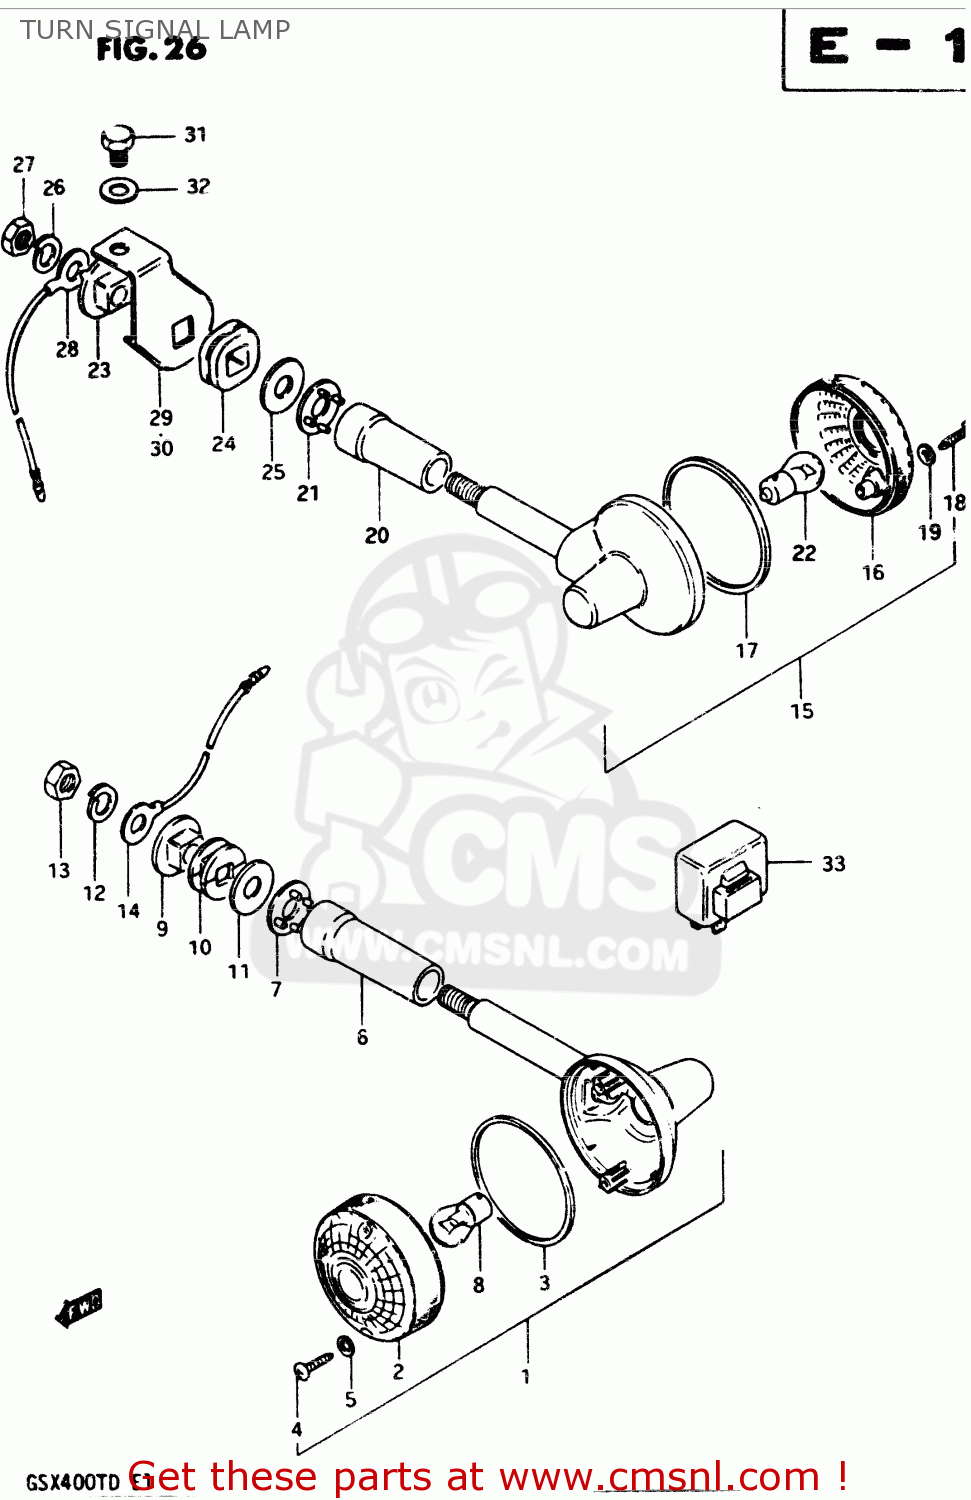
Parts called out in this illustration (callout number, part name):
1	LAMP ASSY FRON
2	LENS
3	GASKET (NAS)
4	SCREW
5	GASKET (NAS)
6	COVER,STAY
7	SPACER
8	BULB(12V21W)
9	SPACER
10	CUSHION
11	WASHER (10.5X30X2.3)
12	LOCK WASHER
13	NUT
14	LEAD WIRE,EARTH
15	LAMP ASSY, REAR TURN SIGNAL
16	LENS
17	GASKET (NAS)
18	SCREW
19	GASKET (NAS)
20	COVER,STAY
21	SPACER
22	BULB(12V21W)
23	SPACER
24	SPACER
25	WASHER (10.5X30X2.3)
26	LOCK WASHER
27	NUT
28	LEAD WIRE,EARTH
29	BRACKET,RR TURNSIGNAL LAMP,R
30	BRACKET,REAR TURN SIGNAL
31	BOLT
32	WASHER
33	RELAY,TURN SIGNAL
